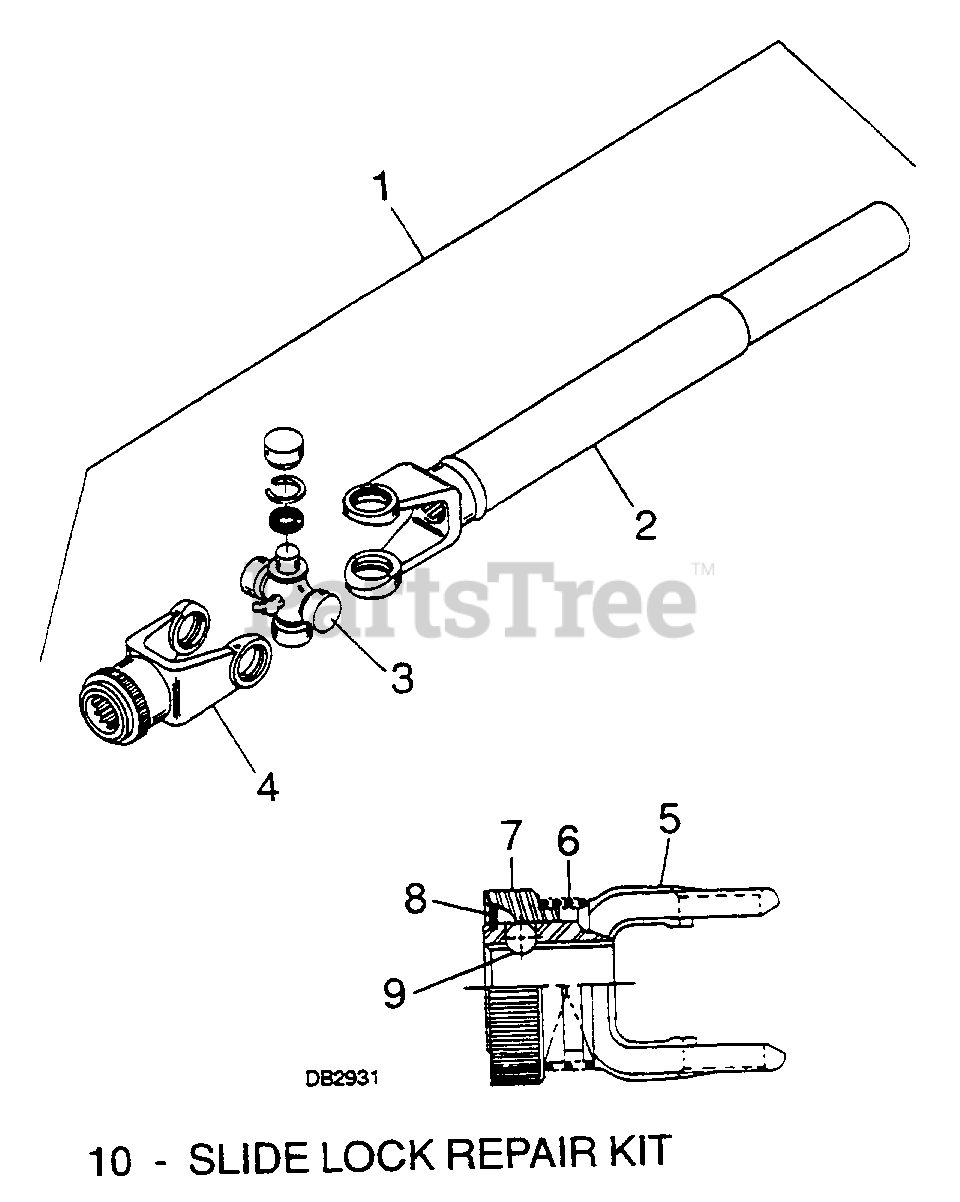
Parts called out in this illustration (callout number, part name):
1	U-Joint drive-rear half assembly
2	Yoke, tube and sleeve assembly 22.5-#0600
2	Yoke tube and sleeve 11.25
3	U-Joint repair kit-#0600
4	Slide collar yoke assembly, 15-tooth #0600
5	Slide collar yoke
6	Spring
7	slide collar
8	Snap ring
9	Steel ball
10	Slide lock repair kit #0600
